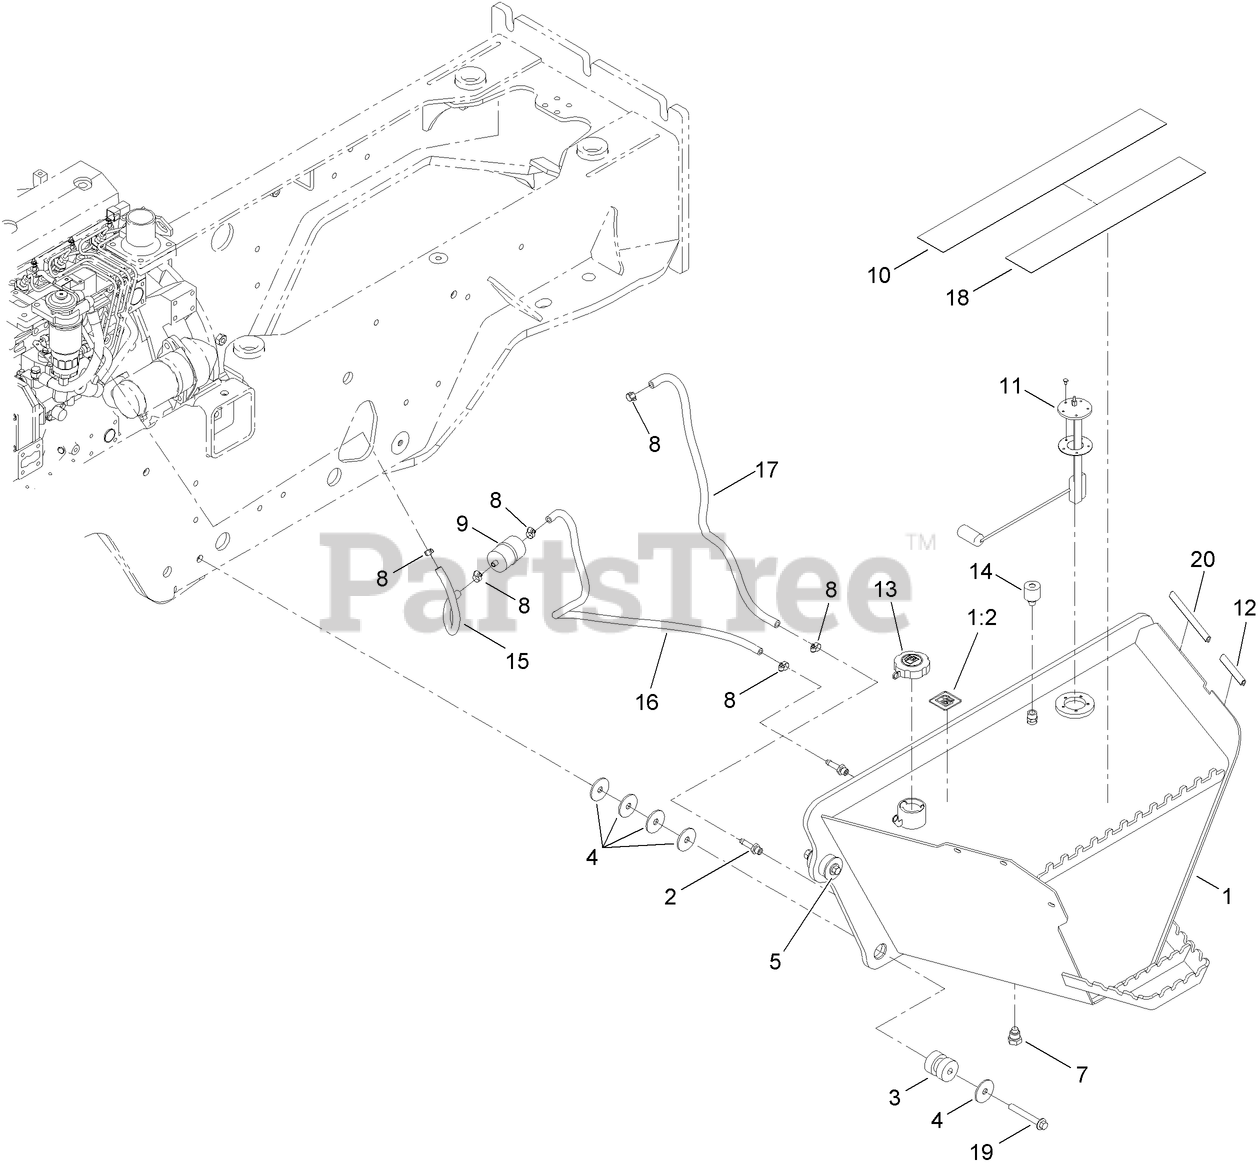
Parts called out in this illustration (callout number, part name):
1	FUEL TANK ASM
1:2	DECAL-DIESEL
2	FITTING-STRAIGHT
3	ISOLATOR-MOUNTING, UNIVERSAL
4	WASHER-FLAT
5	SCREW-HHF
7	PLUG-HEX, MAGNETIC
8	CLAMP-WORM
9	FILTER-INLINE FUEL
10	STRIP-ANTI SKID
11	SENDER-FUEL LEVEL
12	STRIP-SEAL
13	CAP-DIESEL FUEL, NON-VENTED
14	BREATHER
15	HOSE-FUEL
16	HOSE-FUEL
17	HOSE-FUEL
18	TAPE-ANTI SKID, LOWER STEP
19	SCREW-HHF
20	STRIP-SEAL
